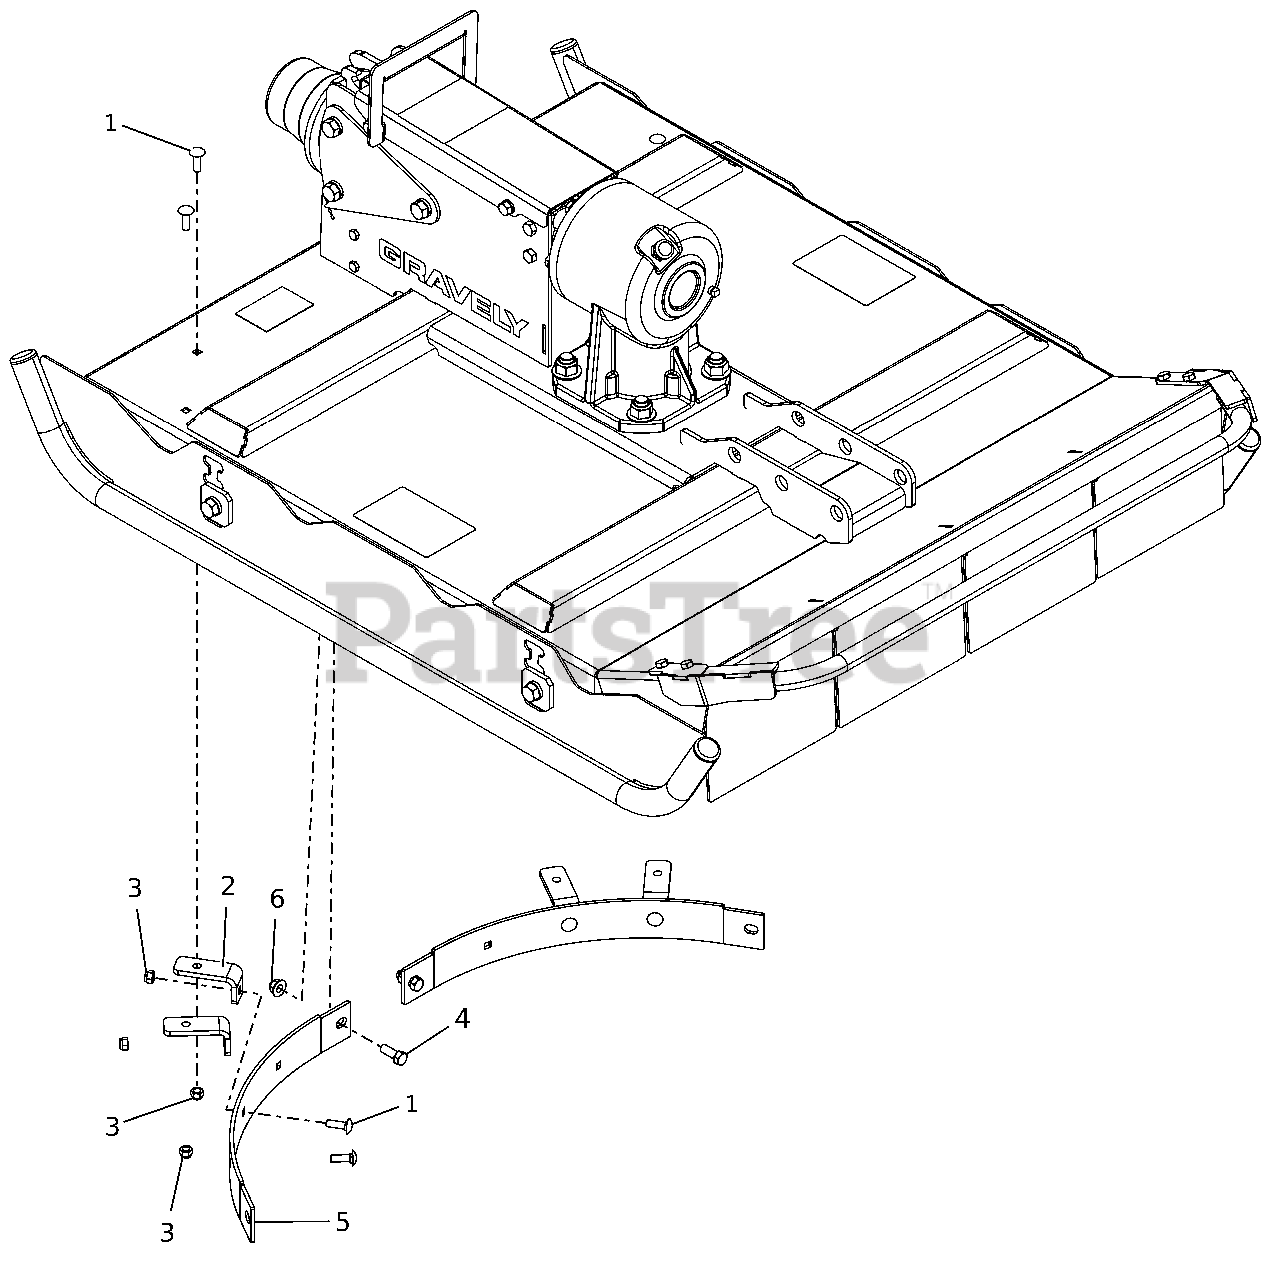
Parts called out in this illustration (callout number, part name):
1	BLT,RHSSN .31-18X1.00 G5 ZCC
2	BRKT, SHIELD
3	NUT,NYL .31-18 G5 ZCC
4	BLT,HEX .38-16X1.00 G5 ZCC
5	BAFFLE, DECK
6	NUT,NYL-FLG .38-16 GF ZCC
